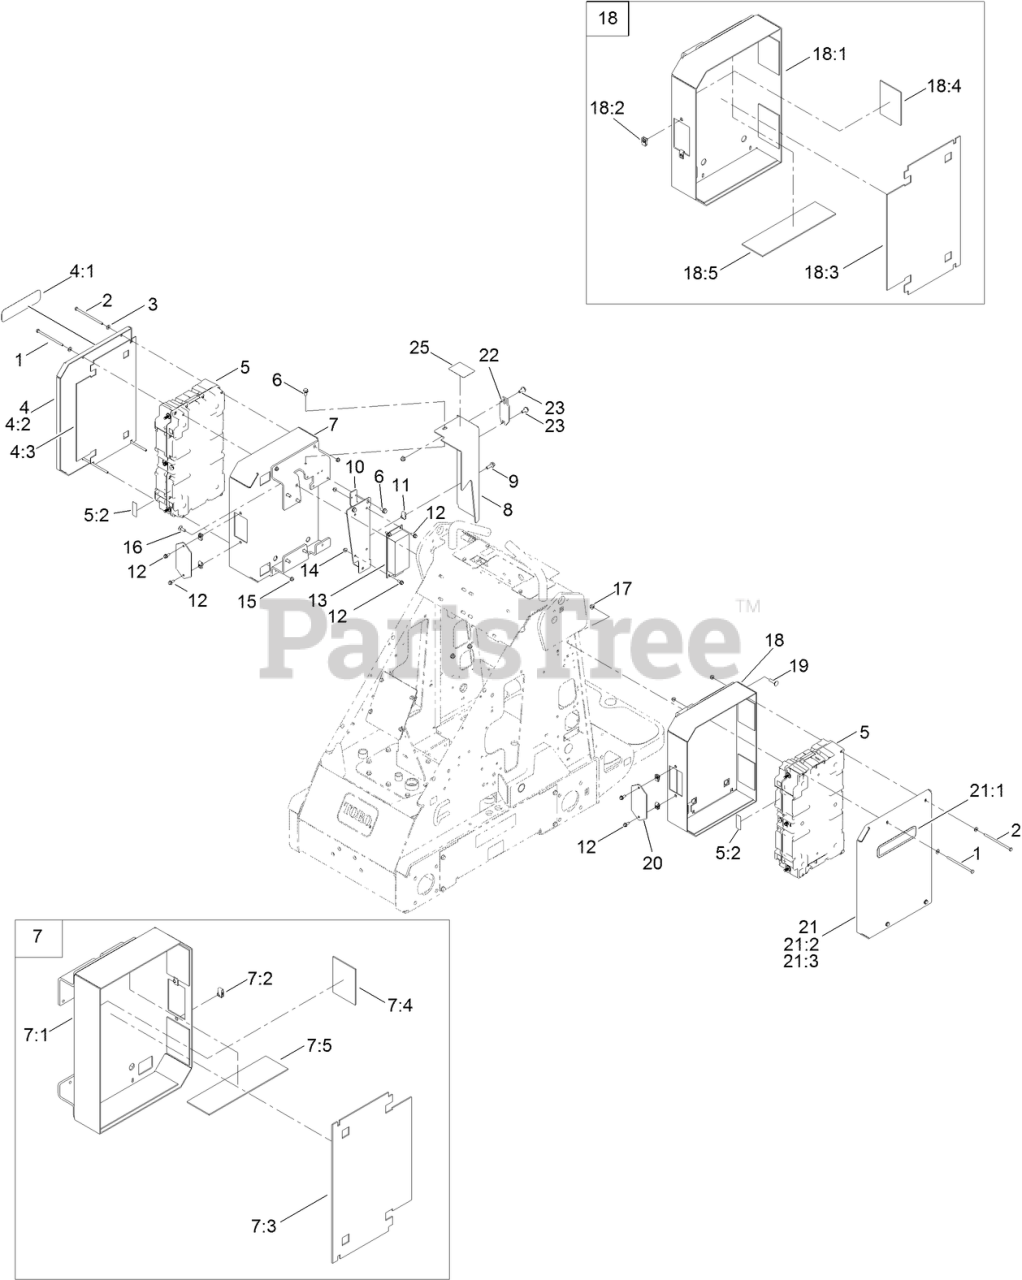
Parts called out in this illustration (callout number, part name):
1	SCREW-HH
2	SCREW-HH
3	WASHER-FLAT
4	COVER-BATTERY ASM
4:1	DECAL - LITHIUM
4:2	COVER-BATTERY
4:3	FOAM-BATTERY, SADDLEBAG
5	BATTERY SERVICE ASM
5:2	DECAL-SAFETY
6	SCREW-HWHTF
7	MOUNT-BATTERY ASM
7:1	MOUNT-BATTERY, RH
7:3	FOAM-BATTERY, SADDLEBAG
7:4	FOAM-BATTERY, SADDLEBAG
7:5	FOAM-BATTERY, SADDLEBAG
8	BRACKET-COVER, CONTACTOR
9	SCREW-HHF
10	BRACKET-MOUNT, CONVERTER
11	NUT-U
12	SCREW-HEAD, FLANGE
13	CONVERTER-DC-DC
14	NUT-HF
15	NUT-FLANGE, NI
16	SCREW-CARR
17	NUT-HF, NI
18	MOUNT-BATTERY ASM
18:1	MOUNT-BATTERY, LH
18:3	FOAM-BATTERY, SADDLEBAG
18:4	FOAM-BATTERY, SADDLEBAG
18:5	FOAM-BATTERY, SADDLEBAG
19	SCREW-CARR
20	PLATE, TERMINAL
21	COVER-BATTERY ASM
21:1	DECAL - LITHIUM
21:2	COVER-BATTERY
21:3	FOAM-BATTERY, SADDLEBAG
22	BRACKET-PORT
23	SCREW-SHOULDER
25	DECAL-CHARGER, WARNING
